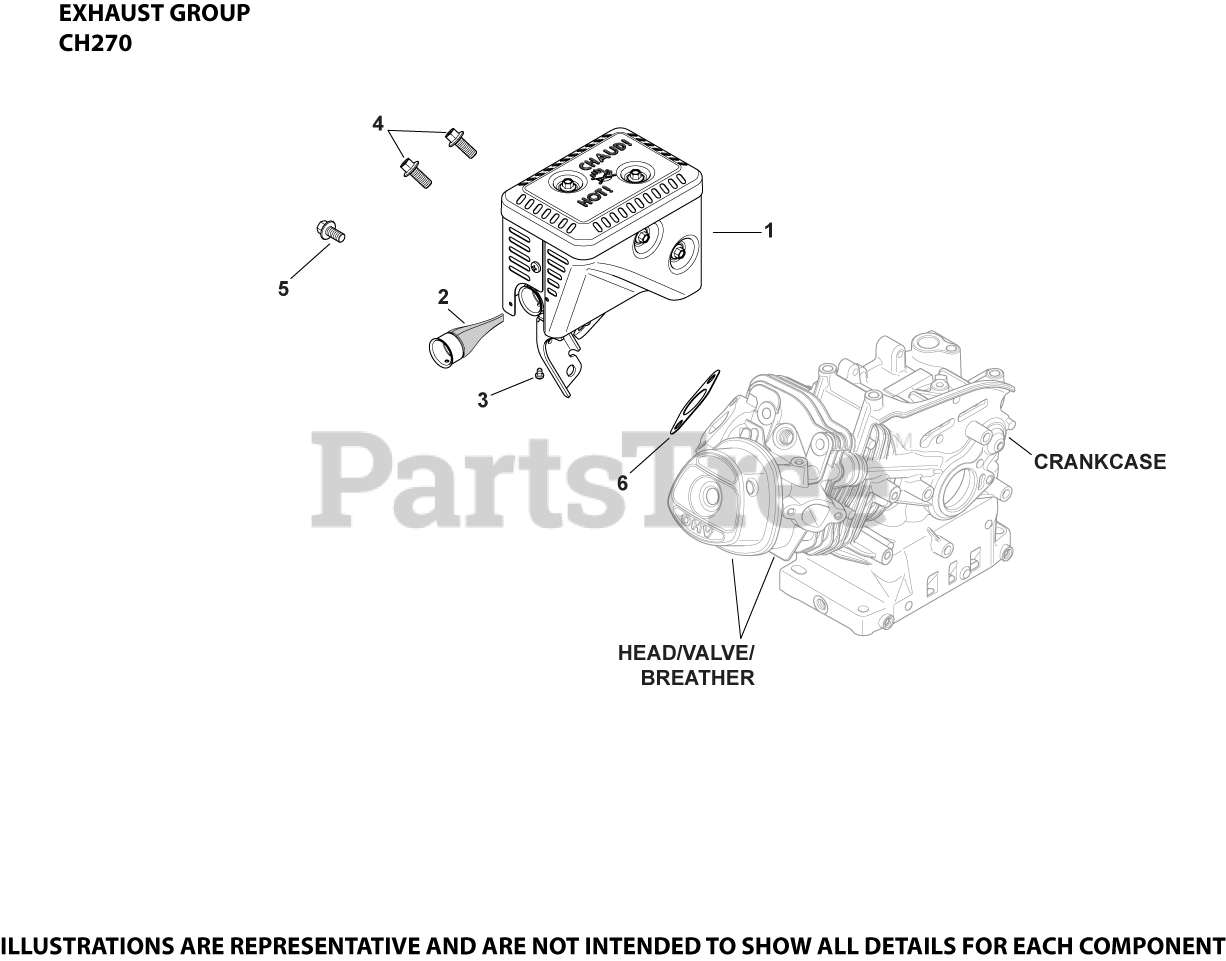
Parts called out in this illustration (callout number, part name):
1	KIT, MUFFLER
4	SCREW, M8 X 20
5	SCREW, FLG 8X1.25X16
6	GASKET, MUFFLER
